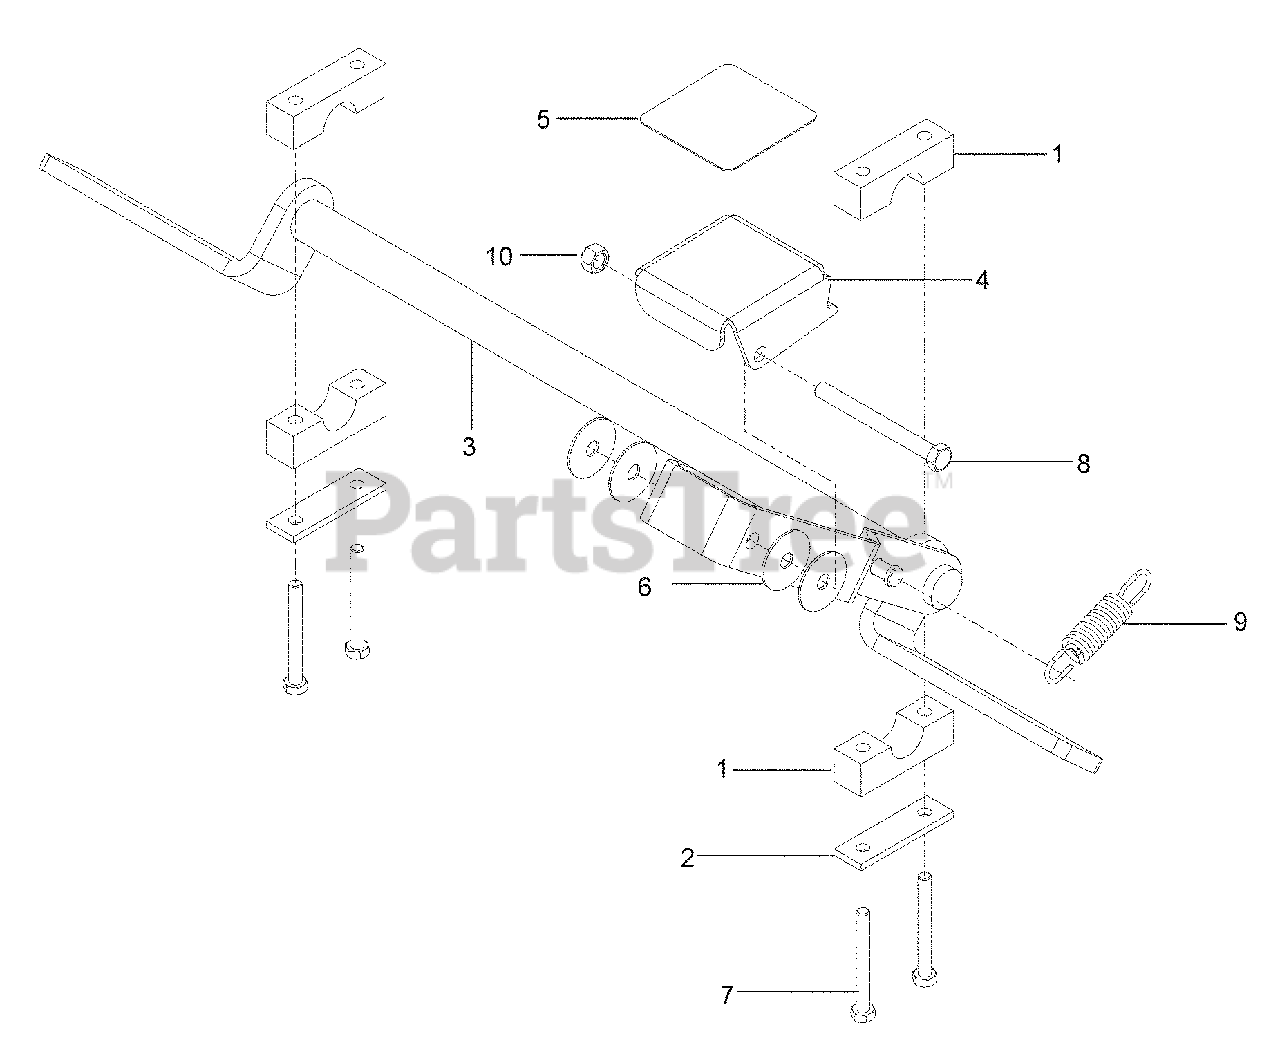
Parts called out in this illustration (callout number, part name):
1	PILLOW BLOCK
2	BAR, REINFORCEMENT
3	BRAKE ASSEM
5	PAD, ANTI-SKID
6	WASHER, FRICTION
7	HCS 5/16-18 x 2¾
8	HCS 3/8-16 x 3¾
9	SPRING, EXTENSION
10	NUT 3/8-16 HEX NYLOC
